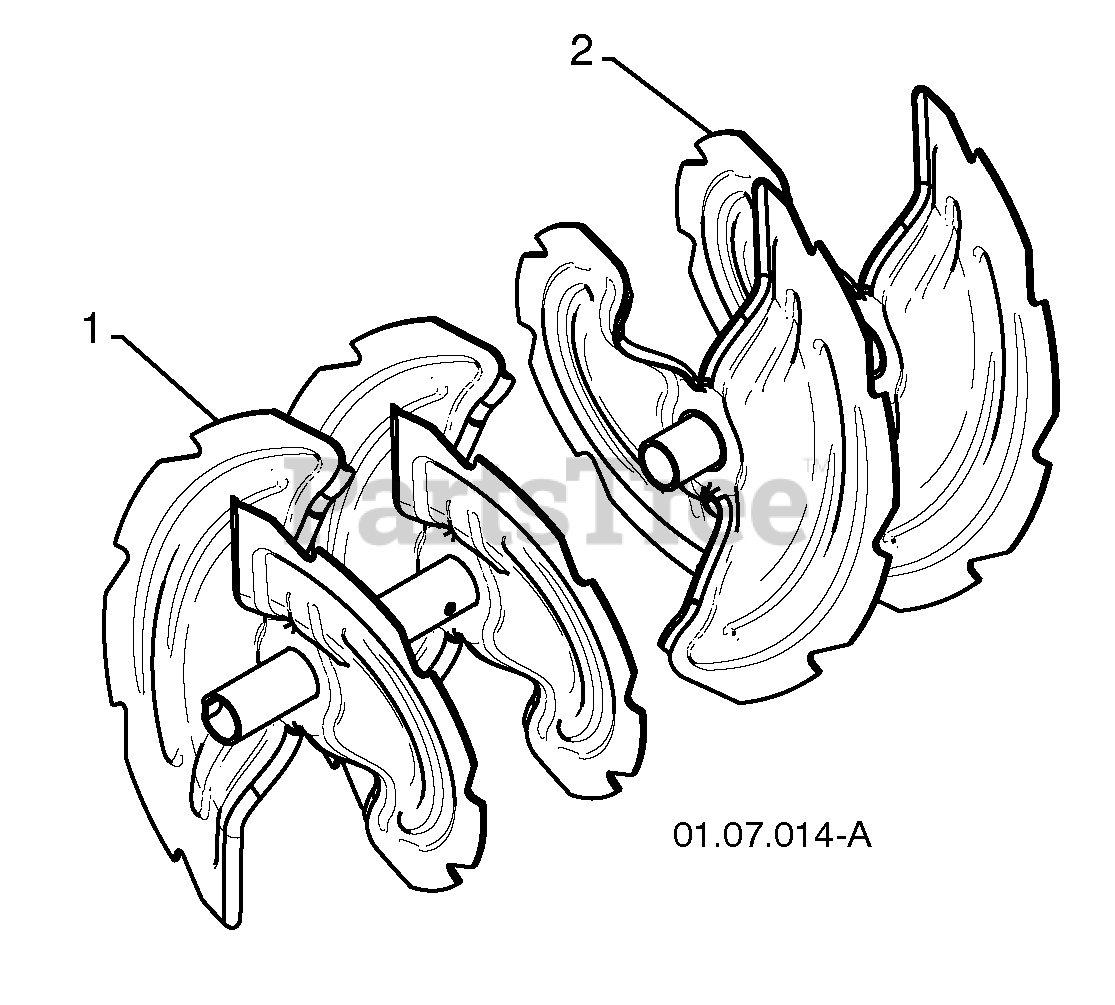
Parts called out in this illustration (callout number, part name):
1	RETAINER.PLASTIC
2	BEARING.BALL.AUGER.FLAT.
3	SCREW, HEX HD 5/16X1
4	SCREW.HEX.HD1/4-20X
5	LOCKNUT.NYLOC.1/4-20
